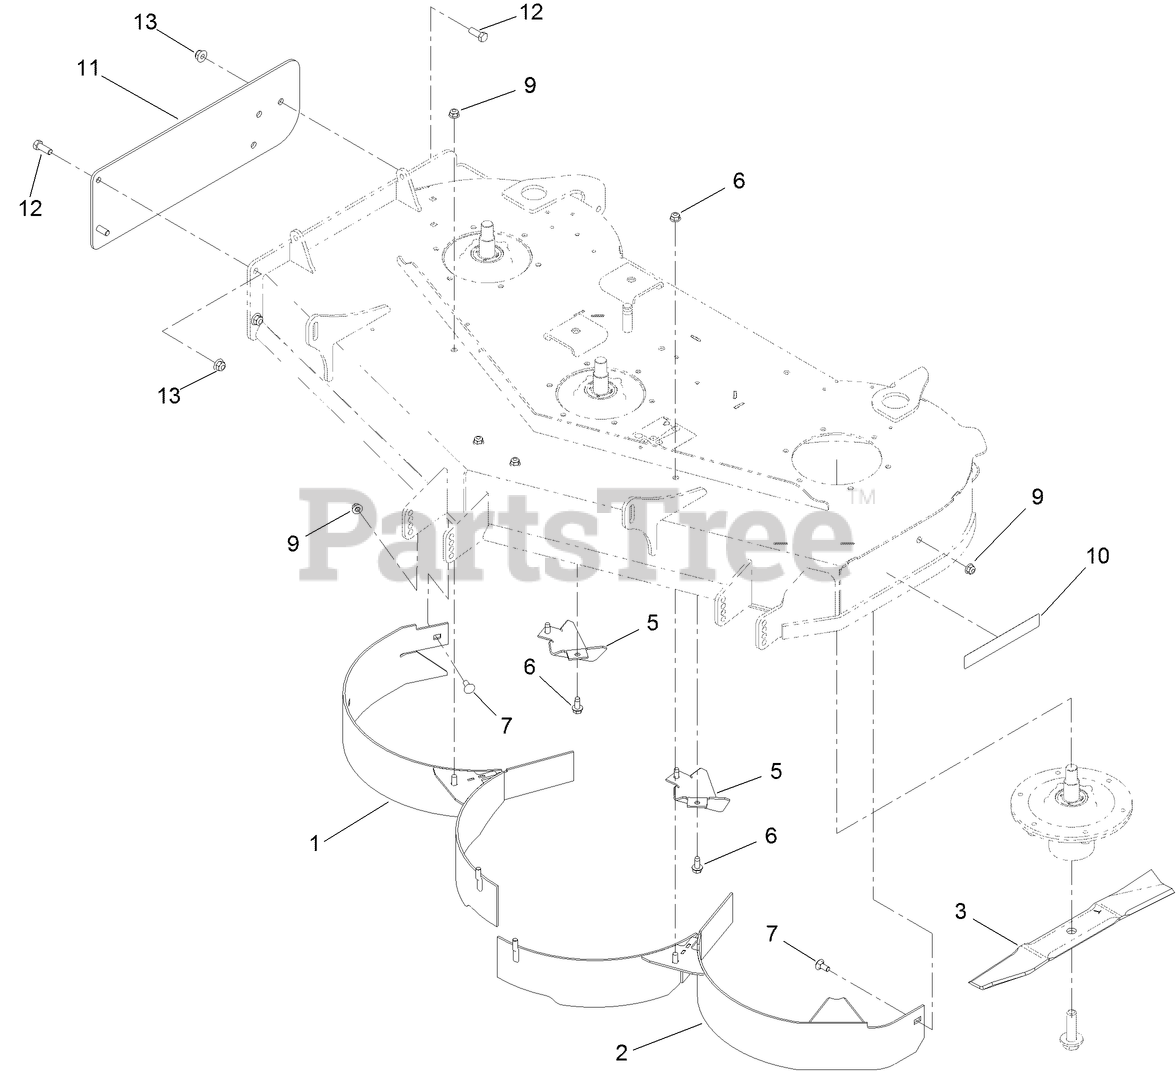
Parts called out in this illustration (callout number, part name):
1	BAFFLE-RECYCLER
2	BAFFLE-RECYCLER
3	BLADE - MULCH 16.50 IN
5	KICKER-FLANGED
6	SCREW-HWHTF
7	BOLT-CARR
9	NUT-HF, NI
10	DECAL-RECYCLER
11	PLATE-DISCHARGE, COVER
12	SCREW-HH
13	NUT-HF, NI
